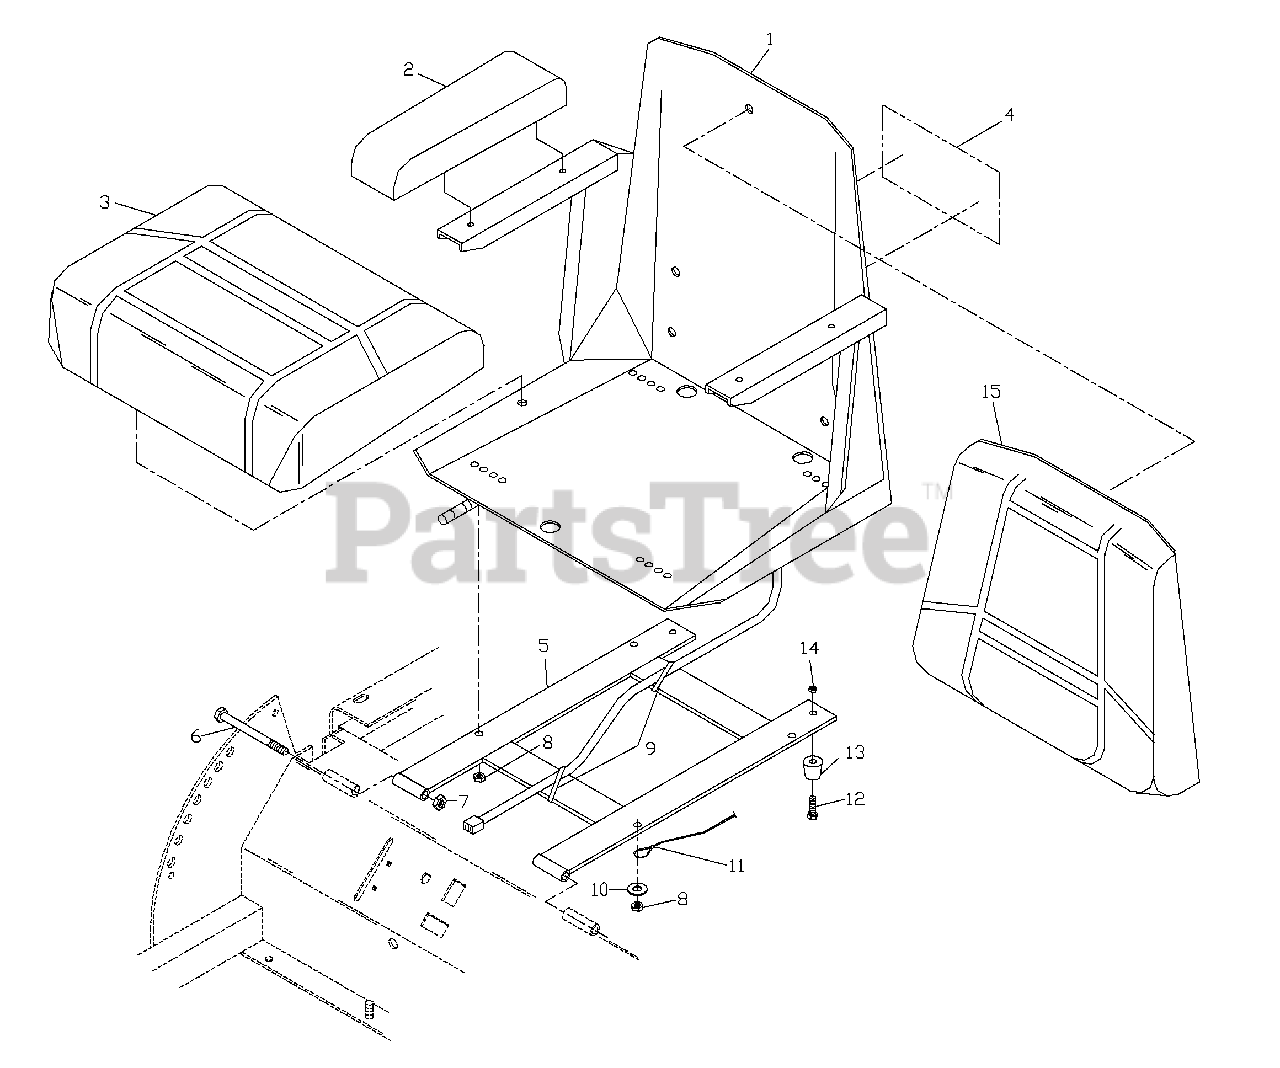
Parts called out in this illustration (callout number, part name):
1	COMPLETE-SEAT
2	ARM REST CUSHION
3	SEAT CUSHION W/SWITCH
4	DECAL, CROWN
5	SEAT MOUNT
6	HCS 3/8C X 4 1/2
7	NUT 3/8C CENTERLOCK
8	NUT 5/16C CENTERLOCK
9	PLASTIC TIE
10	5/16 FLAT WASHER
11	SEAT LANYARD
12	#10-24 X 1/2 SLOTTED SCREW
13	SEAT BUMPER
14	#10-24 NYLOC NUT
15	SEAT BACK CUSHION
